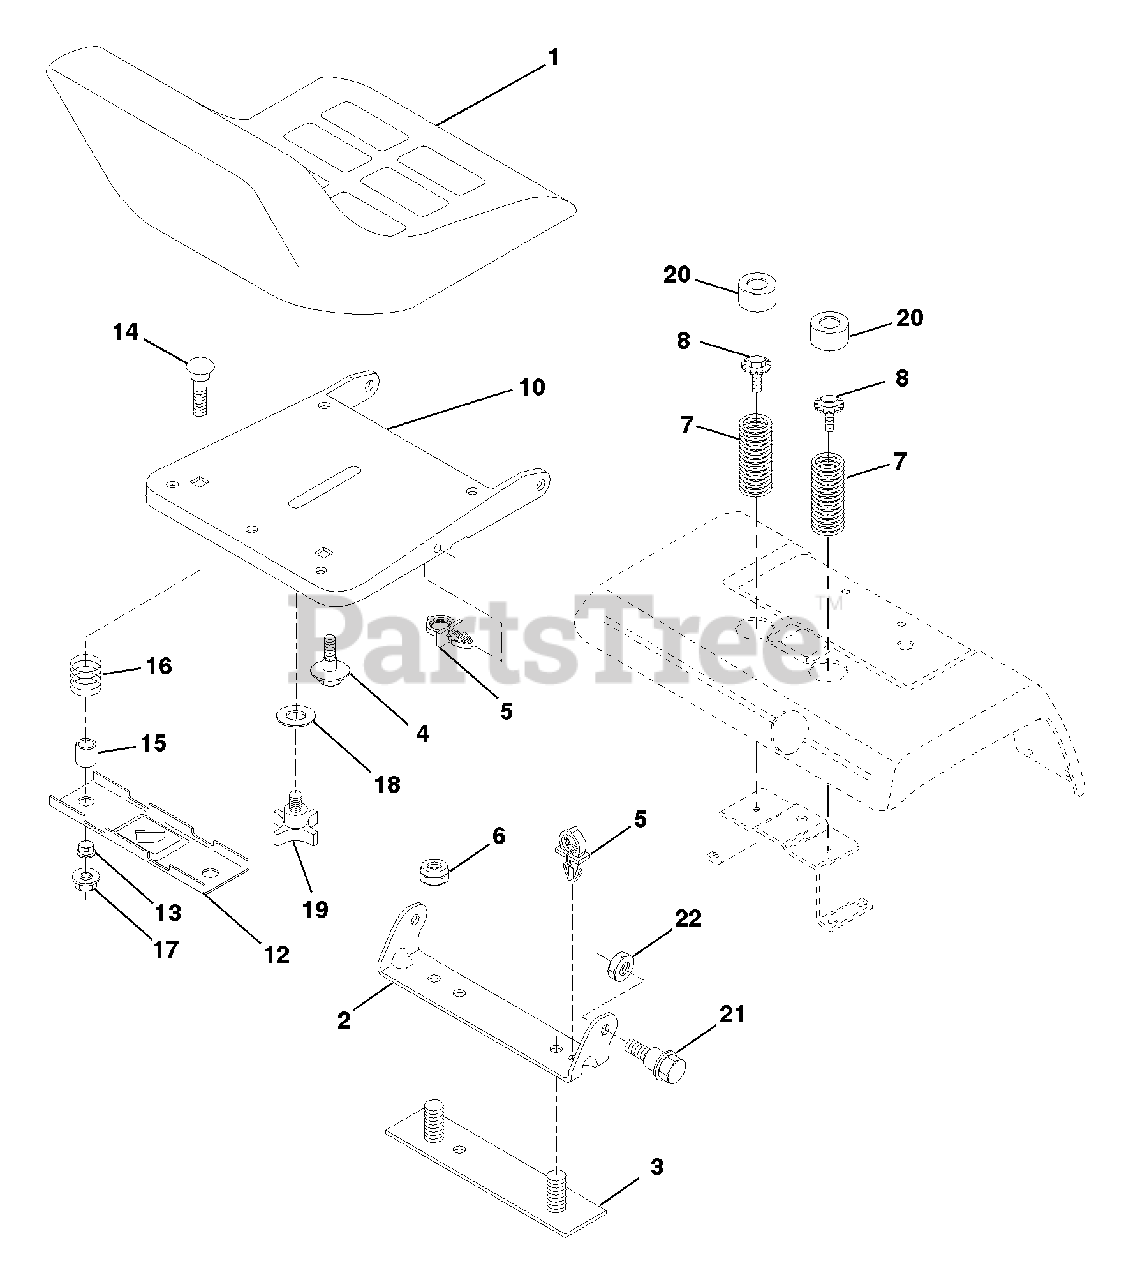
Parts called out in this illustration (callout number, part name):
1	Seat
2	Bracket, Pivot Seat
3	Strap, Fender
4	Bolt, Shoulder 5/16-18 X .62
5	Clip, Push In Hinged
6	Nut, Lock Hex W/Ins. 3/8-16 Unc
7	Spring, Seat Cprsn
8	Bolt 5/16-18 unc x 3/4 W/Sems
10	Pan, Seat
12	Bracket, Mounting Switch
13	Bushing, Snap
14	Bolt, Carriage 1/4-20 X 1-1/2
15	Spacer, Split
16	Spring, Cprsn
17	Nut, Lock 1/4 Lge Flg Gr. 5
18	Washer 17/32 X 1-3/16 X 12 Ga.
19	Knob, Seat 1/2-13 Unc
20	Cap, Spring Seat
21	Bolt, Shoulder 5/16-18 Unc-2A
22	Nut, Crownlock 5/16-18 Unc
